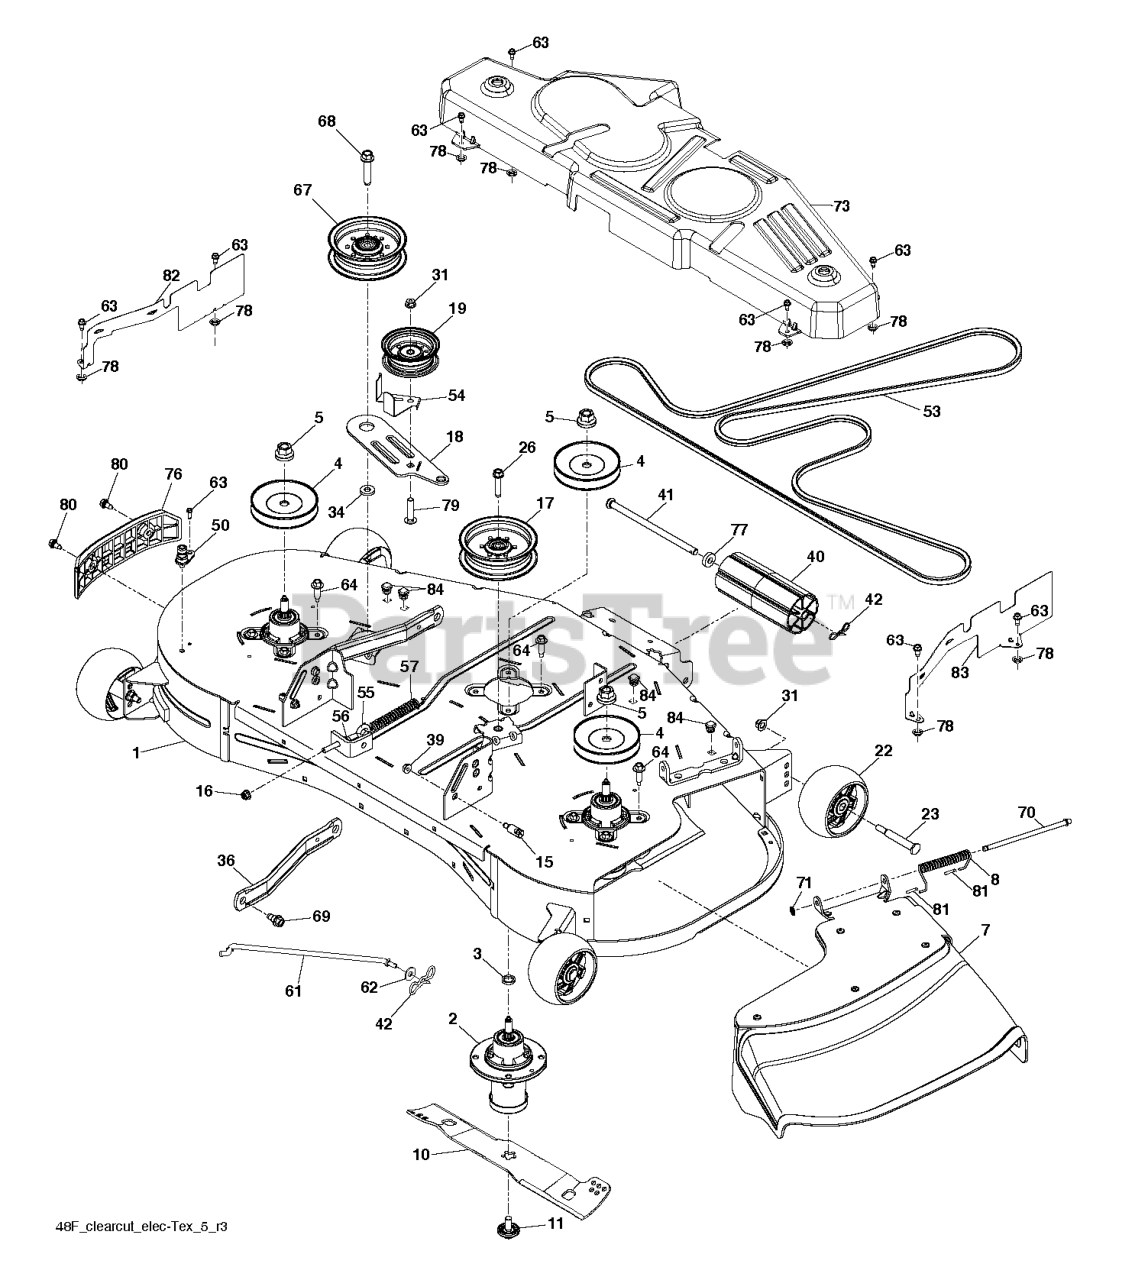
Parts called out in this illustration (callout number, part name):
1	DECK.SVC.48.CC.ASM.668
2	MANDREL ASM, CAST IRON
3	WASHER.SPACER.MANDREL
4	MANDREL PULLEY
7	GSPW Deflectors
8	SPRING.42.FCS.DEFLECTOR
10	BLADE.48.CC.EURO.RES.BGR.MS431
11	BOLT.WASHER.ASM.7/16-2
15	STUD.W/"D"ANTI-ROTATION
16	NUT HEXAGON FLANGE 5/16-18 ST
17	PULLEY.IDLER.MWR.STATI.LH
18	ARM.PNT.CLUTCHING.EDIP
19	PULLEY.IDLER.48"PRIMARY
22	WHEEL.GAUGE.RALLY
26	SCREW.7/16-14 X 2.125.WASHER
31	NUT LOCK FLG 3/8-16 UNC
36	ARM.SUSPENSION.MOWER
40	NOSE ROLLER 48"
42	PIN.COTTER.5/16.BOW TI
50	PORT.WASHOUT
54	GUARD, BELT
55	GSPW Bolts
56	GSPW Hardware
57	SPRING.EXTN.42.FCS.TR.DECK.DRV
64	BOLT.HEX.WASHR.HED.313-18X1.19
67	PULLEY.IDLER.2006
68	BOLT;HEX_3/8-16 X 1.78.CLRZINC
69	BOLT.SHOULDER
71	NUT PUSH M
73	COVER 48 CLEARCUT EURO TRACTOR
76	BUMPER 48 CLEARCUT TRIM SIDE A
77	BUSHING.NOSE.ROLLER
78	PALNUT 1/4
80	SHOULDER BOLT 5/16-18TT
81	CAP-SLEEVE LT
82	SHIELD 48 CLEARCUT EURO TRACTO
83	SHIELD 48 CLEARCUT EURO TRACTO
